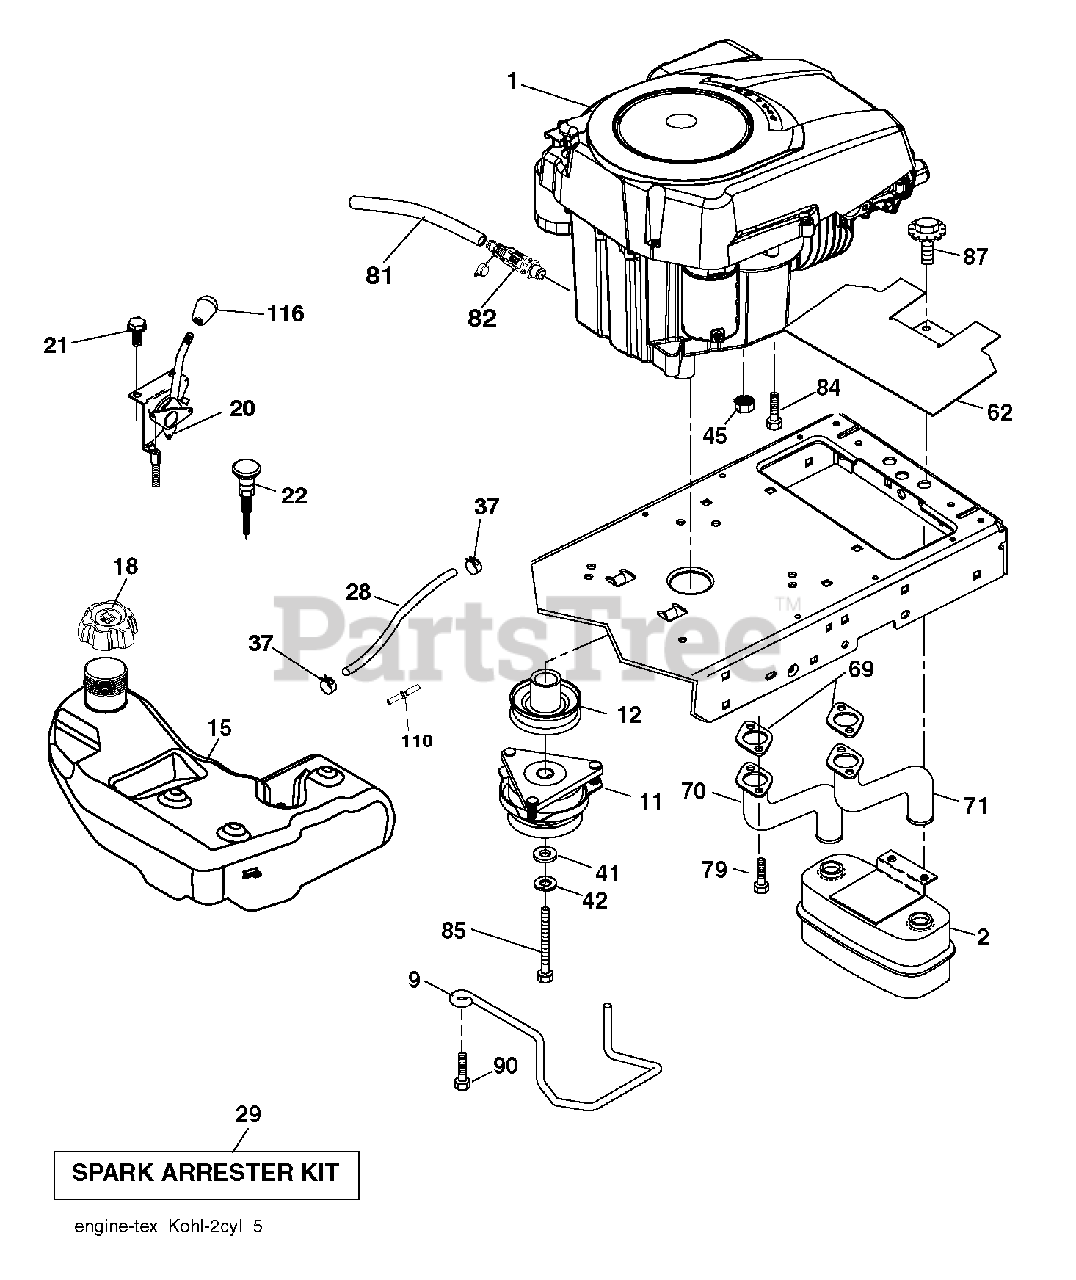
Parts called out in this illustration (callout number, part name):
2	MUFFLER ASSM
9	KEEPER.BELT.ENGINE.4.2
12	PULLEY.ENGINE.TUFFTORQ
15	TANK.ASSY.3.GAL.EPA
18	CAP ASM.FL.RTCHT.3"GRY.E10
20	CONTROL.THROT.PRO
21	SCREW.#10 X 0.750.BOS THREAD
22	CONTROL CHOKE
28	LINE.FUEL.64"REAR.EMIS
29	ARRESTER SPARK (OPTIONAL)
37	HOSE CLAMP
42	LOCKWASHER
62	SHIELD.HEAT.MUFFLER
70	PIPE-EXHAUST LH
71	PIPE-EXHAUST RH
79	SCREW.SOCKET HD.5/16-1
81	TUBE, DRAIN OIL ASM.
82	VALUE.OIL.DRAIN
84	SCREW 3/8-16X1
87	BOLT.5/16-18UNCX1.W/SE
90	SCREW 3/8-16X1
116	KNOB - SHIFT
